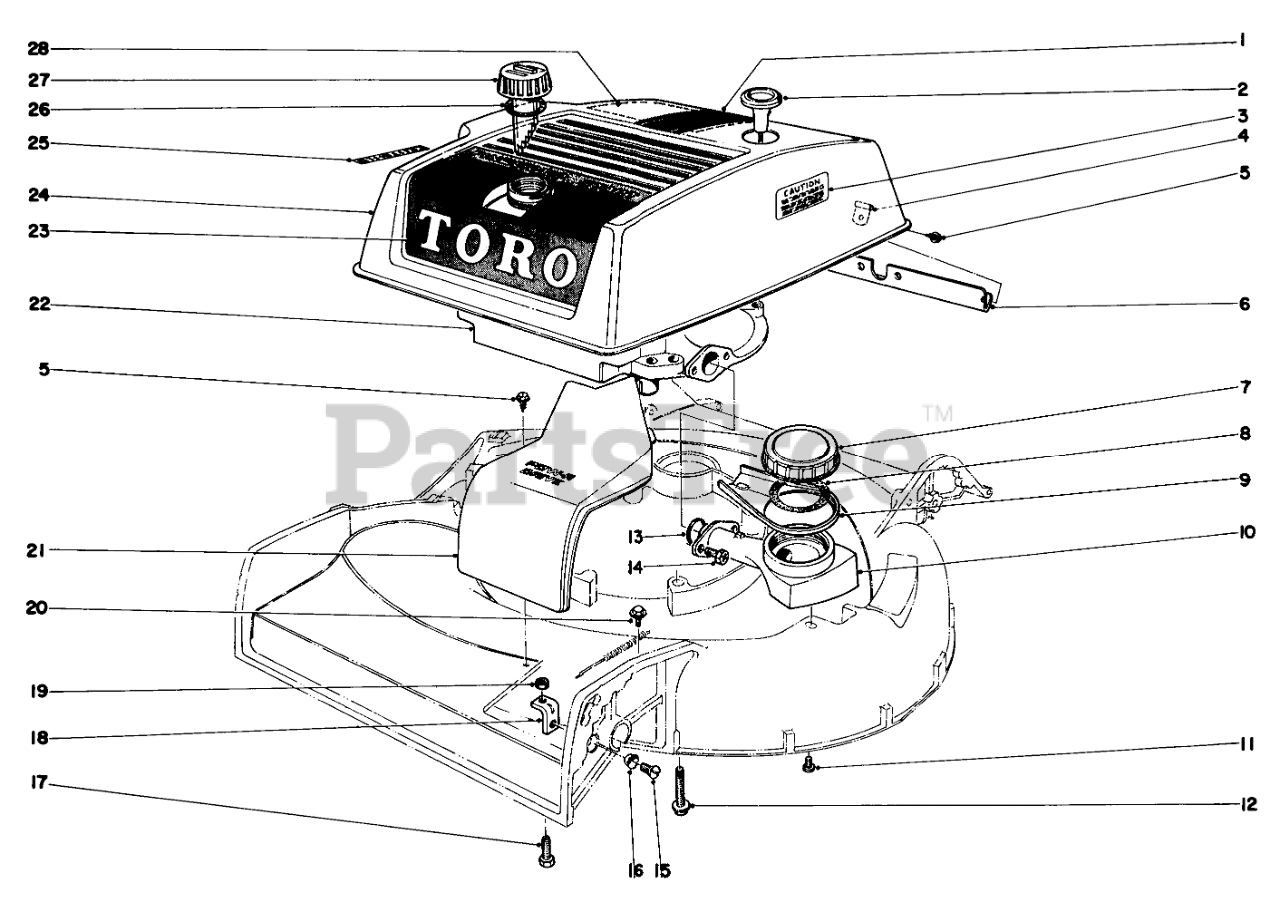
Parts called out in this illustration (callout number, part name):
1	Decal
2	Handle, Rope
3	Decal
4	Hinge
5	SCREW-HWHTF
6	Shroud Bracket
7	Oil Gauge Cap
8	VISUAL OILER GASKET
9	Spout
10	Oil Gauge
11	10-16 X 3/8 THDG SCREW
12	3/8-16 X 2-3/4 CAPSCR
13	O RING
14	Screw
15	5/16-18X5/8 FLT HD MS
16	Lockwasher
17	SCREW
18	ADJ BRACKET
19	NUT-JAM
20	SCREW-HHF
21	Cover
22	Engine
23	Decal
24	Shroud
25	Decal, Air Cleaner
26	Gasket
27	Gas Cap
28	Decal-Maintenance
